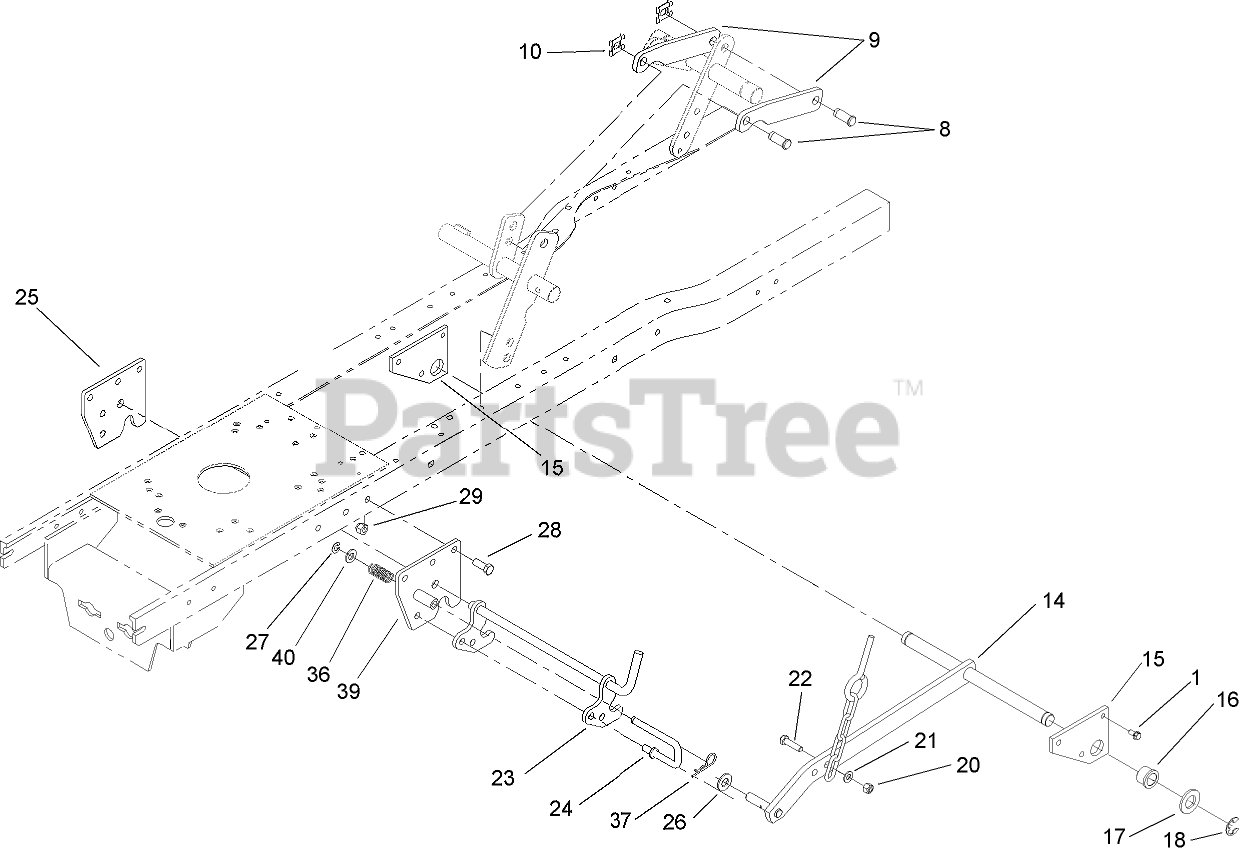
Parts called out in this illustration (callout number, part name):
1	SCREW-HWHTF
8	PIN-CLEVIS
9	STRAP-LINK, LIFT
10	CLIP-PIN
14	LIFT BAR ASM
15	Plate-Lift, Rear
16	BUSHING-FLANGE
17	WASHER-FLAT
18	E-RING
20	NUT-LOCK, NI
21	WASHER-PLAIN
22	SCREW-HH
23	MIDHITCH LATCH ASM
24	ROD-CATCH
25	Plate-Hitch
26	WASHER-FLAT
27	RING-RETAINING
28	SCREW-HH
29	NUT-LOCK, NI
36	SPRING-COMPRESSION
37	PIN-HAIR
39	MIDHITCH ASM
40	WASHER-FLAT
